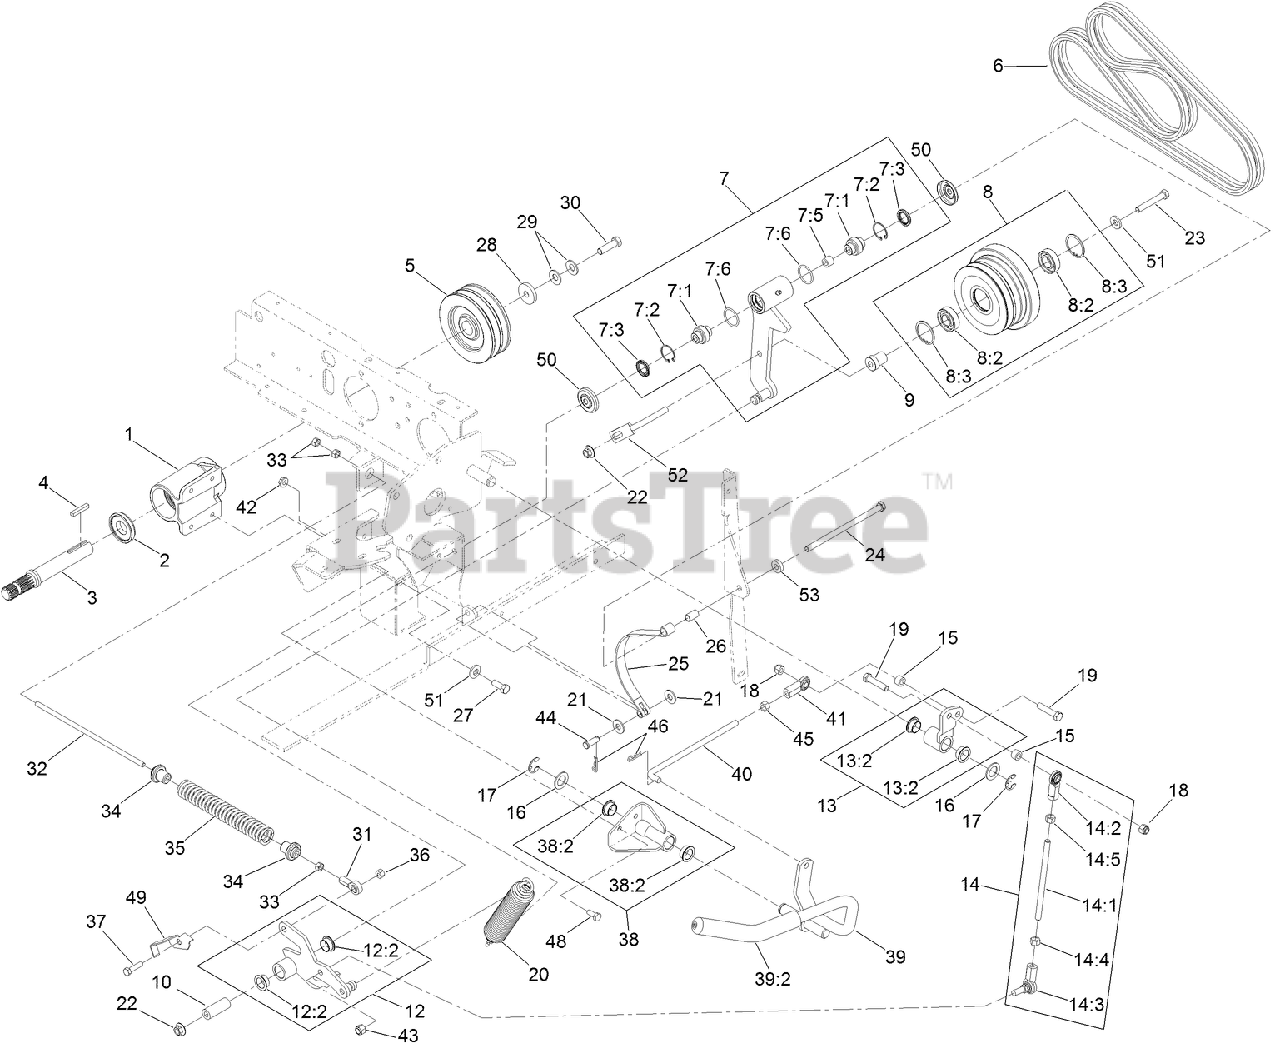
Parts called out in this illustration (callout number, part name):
1	JACKSHAFT ASM
2	SPACER-GUARD, BOTTOM
3	JACKSHAFT
4	KEY-SQUARE
5	SHEAVE
6	BELTS-PAIR, MATCHED
7	IDLER PIVOT ASM
7:1	BEARING-SPHERICAL
7:2	RING-SNAP
7:3	SEAL-LIP, SINGLE
7:5	BUSHING-LEVER, LIFT
7:6	O-RING
8	IDLER SHEAVE ASM
8:2	BEARING-BALL
8:3	RING-RETAINING
9	SPACER-IDLER
10	BUSHING
12	ARM ASM
12:2	BUSHING-BRONZE
13	ARM ASM
13:2	BUSHING-BRONZE
14	CLUTCH LINK ASM
14:1	ROD-LINKAGE
14:2	JOINT-BALL END, LH
14:3	BALLJOINT-RH
14:4	NUT-HEX
14:5	NUT-HEX, LH
15	SPACER
16	WASHER
17	E-RING
18	NUT-LOCK, NI
19	SCREW-HH
20	SPRING-EXTENSION
21	WASHER-FLAT
22	NUT-HF
23	SCREW-HH
24	SCREW-HH
25	BAND-BRAKE
26	SPACER
27	SCREW-HH
28	WASHER-CLUTCH
29	WASHER-SPRING
30	SCREW-HH
31	BALLJOINT-RH
32	LINKAGE-ROD, PTO BRAKE
33	NUT-HEX
34	BUSHING-SPRING
35	SPRING-BRAKE
36	NUT-LOCK, NI
37	SCREW-HH
38	PIVOT ASM
38:2	BUSHING-BRONZE
39	PTO HANDLE ASM
39:2	GRIP-LEVER, CONTROL
40	LINK-HANDLE
41	JOINT-BALL, END
42	NUT-HF
43	NUT-LOCK
44	PIN-CLEVIS
45	NUT-HEX
46	PIN-COTTER
48	SCREW-HH
49	SWITCH-FLAG
50	GUARD-TOP
51	WASHER-BELLEVILLE
52	GUIDE-BELT
53	SPACER
